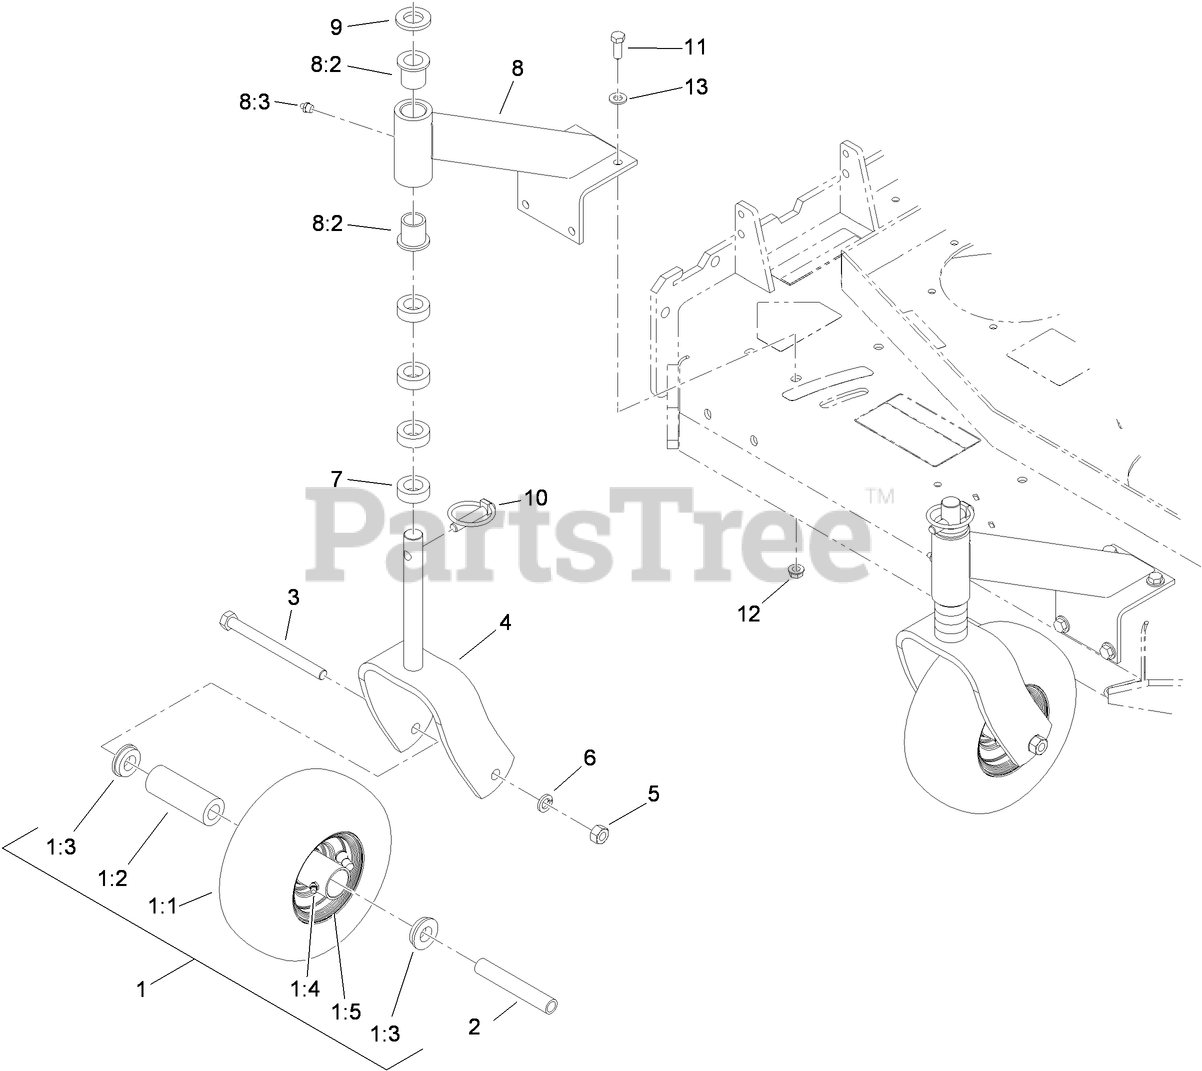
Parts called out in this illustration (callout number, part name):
1	WHEEL AND TIRE ASM
1:1	TIRE
1:2	BEARING
1:3	BUSHING
1:4	FITTING-GREASE
1:5	WHEEL
2	SPACER
3	SCREW-HH
4	FORK
5	NUT-HH
6	WASHER-LOCK
7	SPACER-CASTER
8	SUPPORT ASM
8:2	BEARING-FLANGED
8:3	FITTING-GREASE
9	WASHER-FLAT
11	SCREW-HH
12	NUT-HHF, WHIZ
13	WASHER-FLAT
